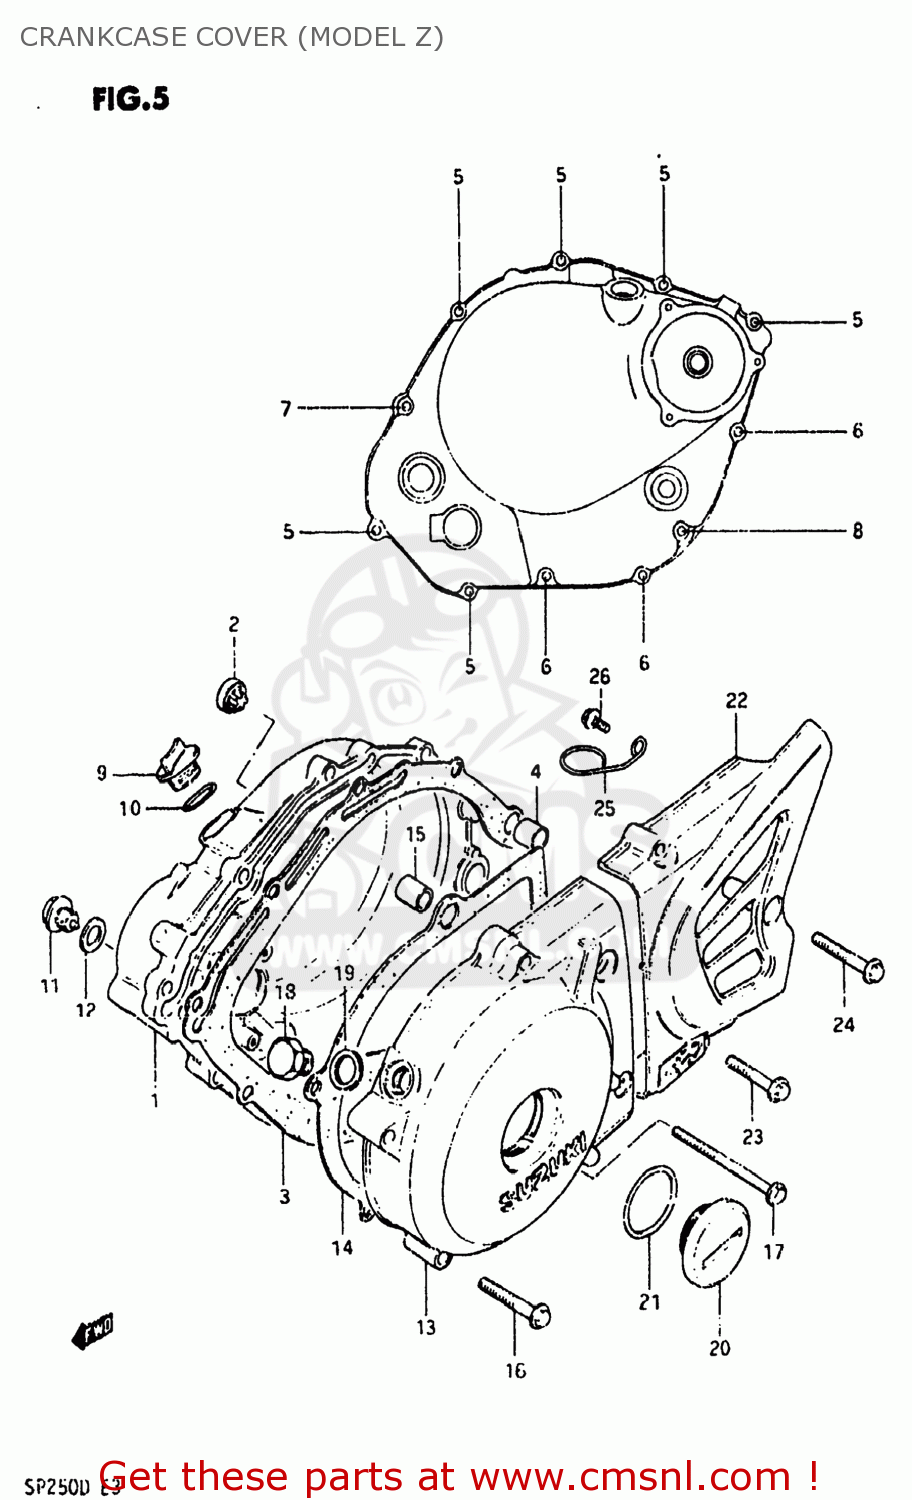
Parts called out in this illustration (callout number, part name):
1	COVER,CLUTCH
2	LENS,OIL LEVEL CHECK
3	GASKET,CLUTCH COVER (MCA)
4	PIN
5	BOLT
6	BOLT (6X35)
7	BOLT (6X40)
8	BOLT
9	PLUG(20X10)
10	O RING(D:3.1,ID:16.8)
11	PLUG (14X12)
12	GASKET(14X19.2X2) (NAS)
13	COVER
14	GASKET,MAGNETO COVER (MCA)
15	PIN
16	BOLT (6X35)
17	BOLT (6X50)
18	PLUG,12X9
19	GASKET(12.1X16.2X3.7) (NAS)
20	PLUG
21	O RING(D:3.1,ID:32.7)
22	COVER,ENGINE SPROCKET
23	BOLT (5*30)
24	BOUT
25	GUIDE
26	BOLT
